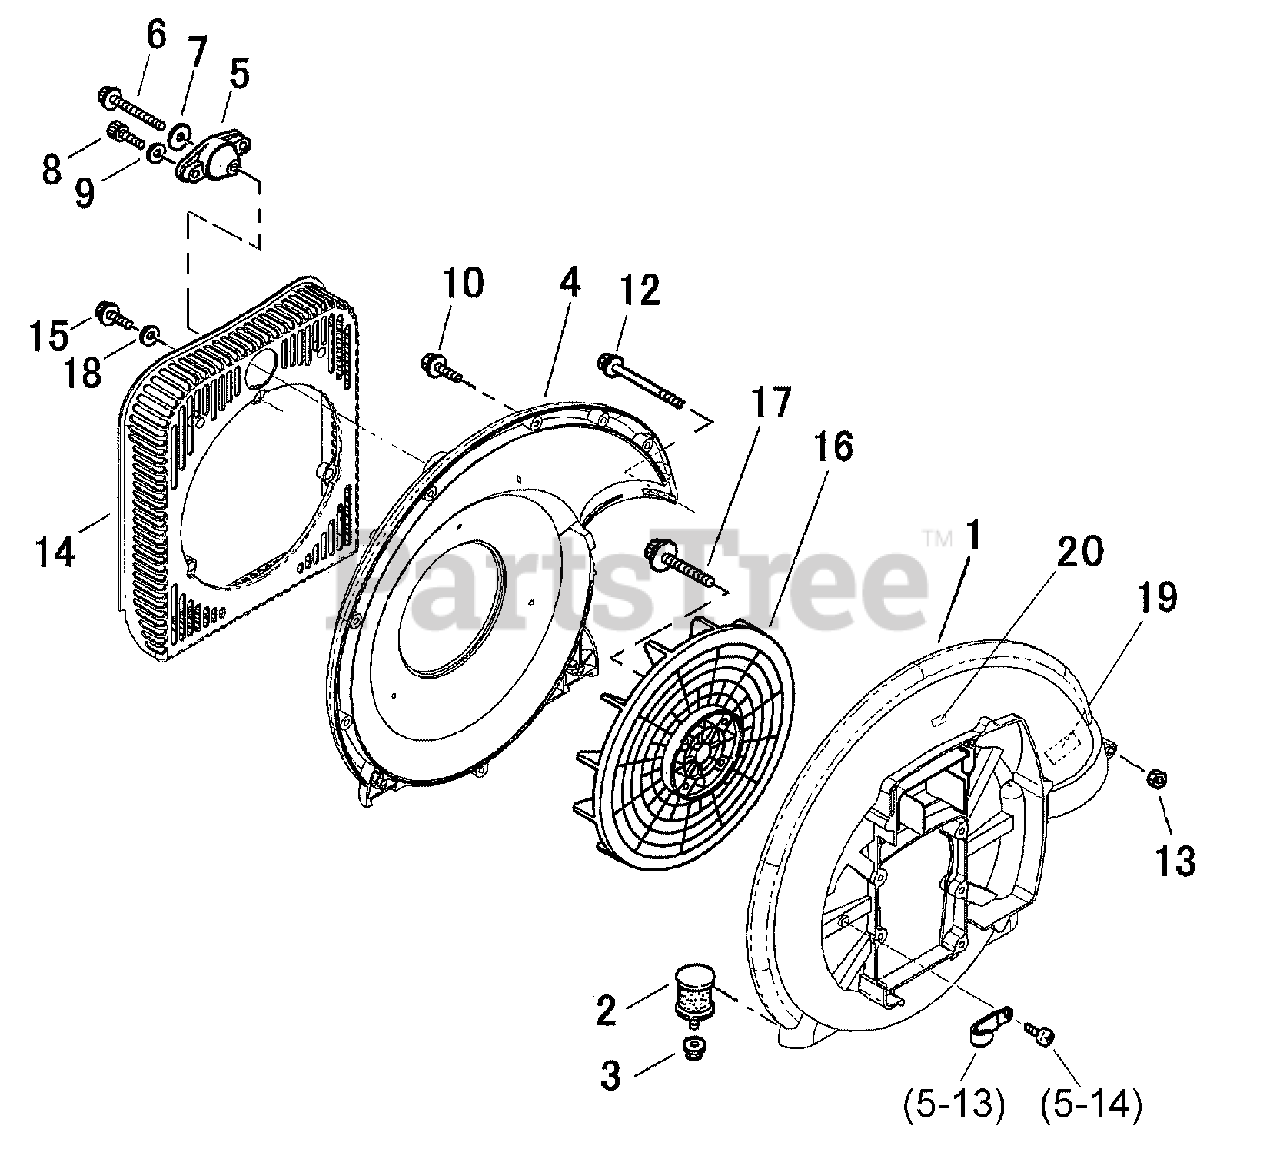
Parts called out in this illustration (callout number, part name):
1	COVER, FAN - OUTER
2	CUSHION
3	NUT - 6 -- FLANGE
4	COVER, FAN - LEFT
5	CUSHION
6	BOLT - 5 -- TAPPING
7	COLLAR - 25X5.5X2
8	SCREW - 5X16
9	COLLAR
10	BOLT - 5X20
12	SCREW - 5X70
13	NUT - 5
14	COVER, INTAKE
15	BOLT - 5X20
16	FAN
17	BOLT - 6X40
18	WASHER - 5
19	LABEL - CAUTION
20	LABEL - NOISE
